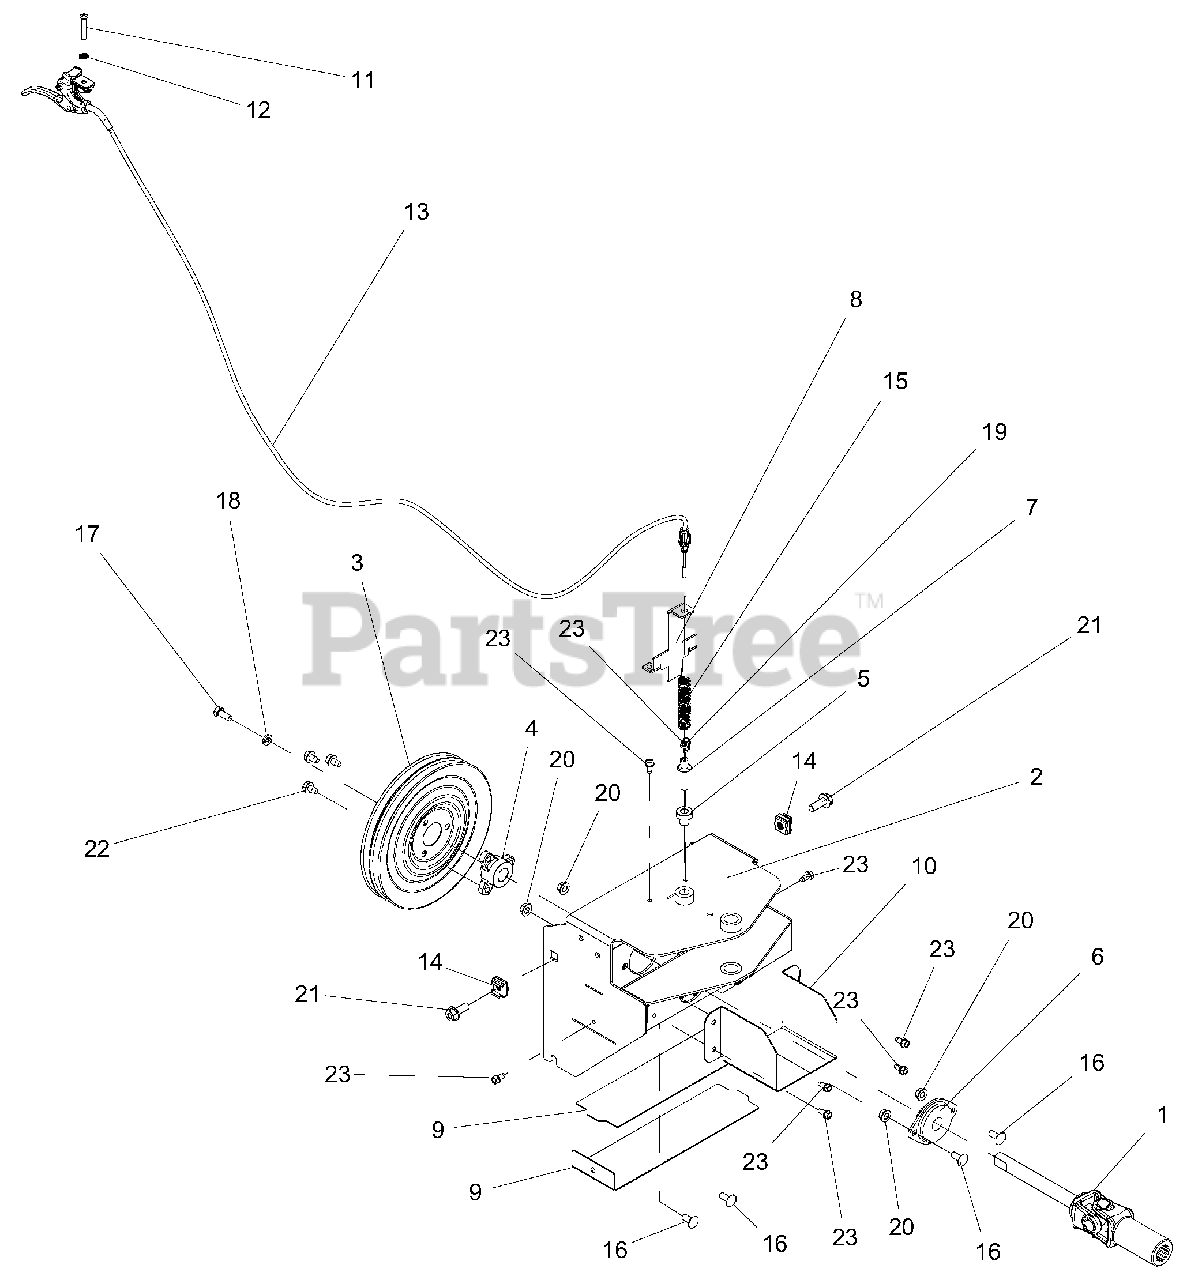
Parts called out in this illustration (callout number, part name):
1	DRIVELINE, SERIES 07 (U-JOINT)
2	ADAPTER, BRUSH
3	PULLEY, SPIN FORM DUAL GROOVE
4	PULLEY HUB, BOLT-ON D-BORE .75
5	SPACER -FLANGED .390X.500X.781
6	BEARING, 2 BOLT FLANGE -.75 ID
7	PIN, ADJUSTABLE ANGLE BRUSH
8	BRKT, PIN HOLDER
9	GUARD, BRUSH PTO
10	GUARD, BRUSH U-JOINT
11	SCR-MCH .25-20X1.50 OVAL HD
12	WSHR-LK-INT .250 TH TYA
13	CABLE, REMOTE BRUSH LOCK
14	NUT-RETNR .38-16 TINRMAN
15	SPRING, COMPRESSION
16	@BLT-RDHDSQNK .31-18X.75 G5YZ
17	BLT-HEX .31-24X.75 YWZC GR5
18	WSHR-LK .312X.097 HVY YWZC
19	@NUT-HEX 10-24 YWZC
20	@NUT-LK-TOP-FLG .31-18 YWZC
21	BLT-SERHFWH .375-16X1.0 YWZC
22	@SCR-TAP .31-18X.50 HWH TR YWZ
23	SCR-TAP .25-20X.50 HWH TR YWZ
